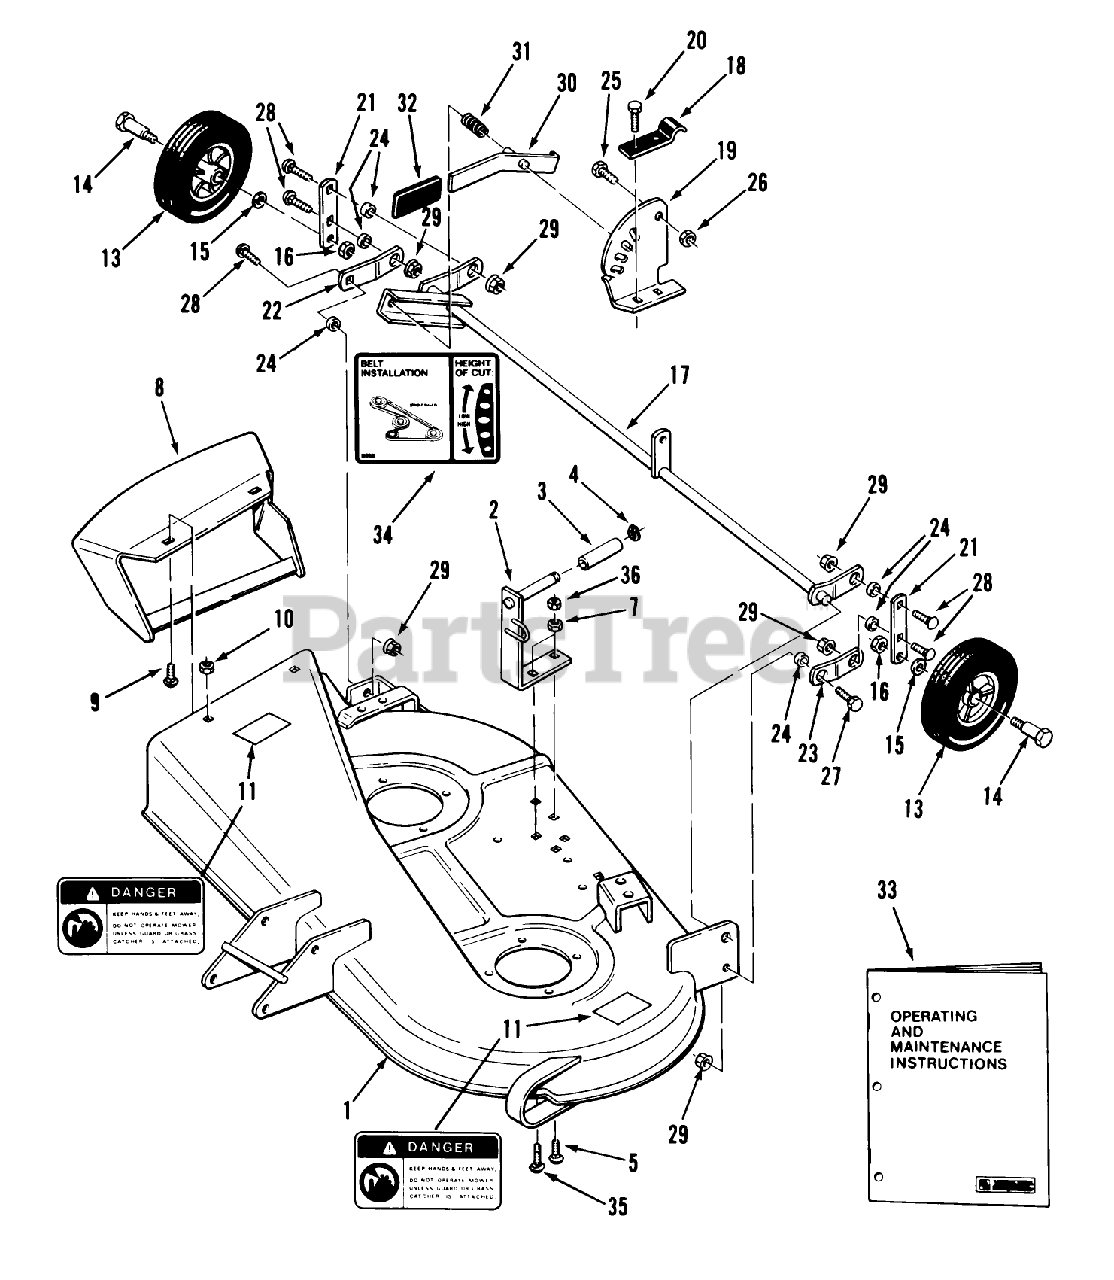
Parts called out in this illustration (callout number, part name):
1	ASSY 32" MOWER SI *R
20	Bolt
24	SPACER
31	SPRING-COMPRESSION
33	Operating Maintenance Instructions
